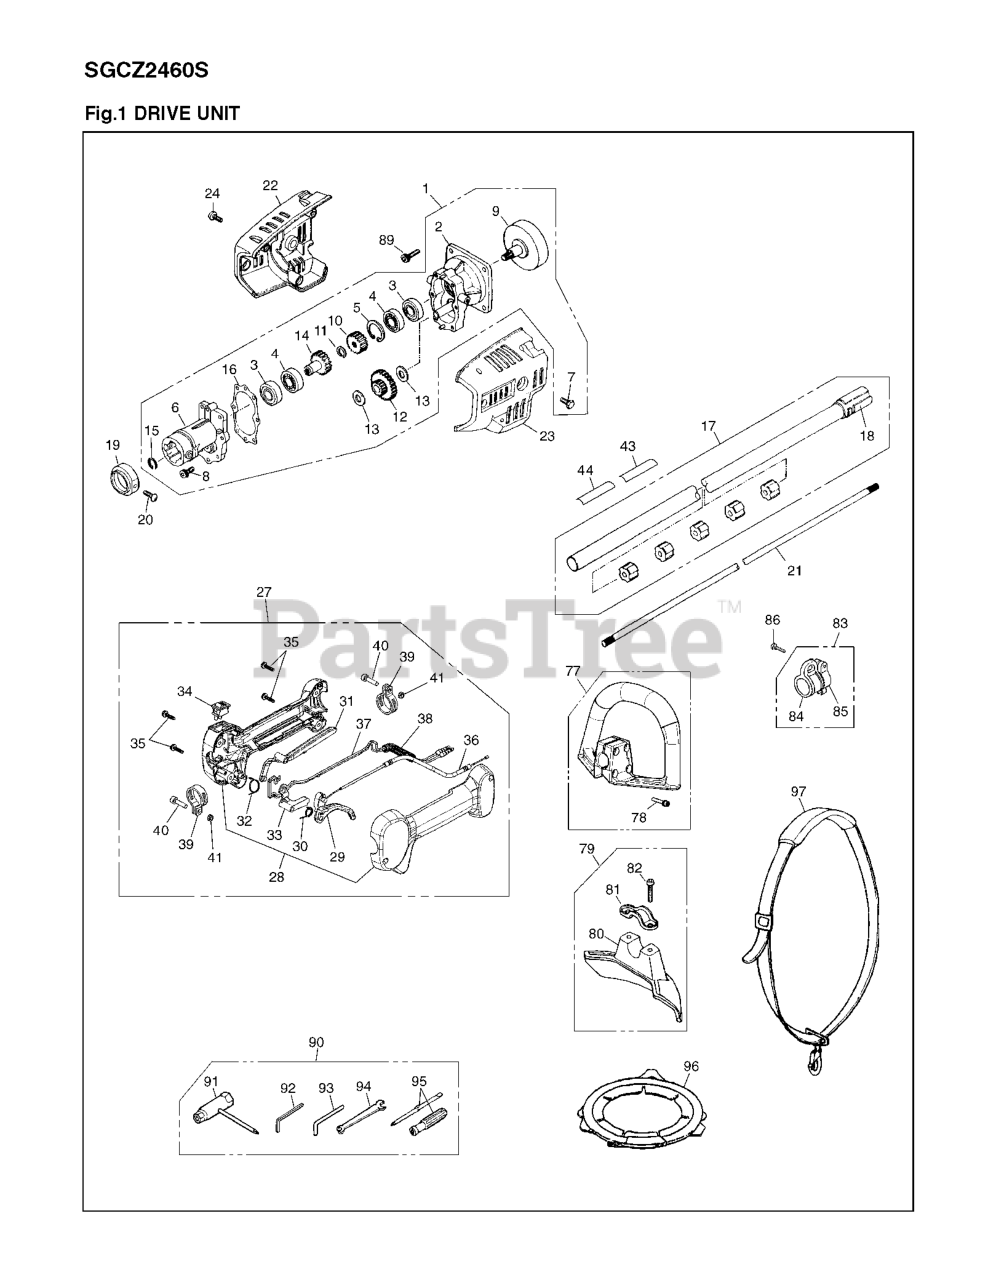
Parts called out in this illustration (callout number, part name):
1	MISSION ASSEMBLY
2	CASE,REAR COMP(RPLS 3805-11101
6	CASE, FRONT
7	BOLT, M6 x 8
8	BOLT
9	DRUM
10	GEAR, PINION
11	RING, SNAP
12	GEAR (RPLS 380511330)
13	WASHER***
14	GEAR, WHEEL
16	GASKET (RPLS 380511411)
17	PIPE COMP (RPLS 380512100)
18	CUSHION (RPLS 380512130)
19	CAP
20	SCREW, M5 x 10
21	SHAFT
22	COVER,RIGHT(RPLS380511510)***
23	COVER, LEFT(RPLS 380511520)***
24	SCREW
27	GRIP ASSY
28	GRIP HALF SET
29	LEVER, THROTTLE
30	SPRING, THROTTLE
31	LEVER FOR GRIP (RPLS -0600)
32	SPRING JOINT
33	LEVER JOINT
36	THROTTLE CABLE
38	TUBE
40	SCREW
41	NUT
43	LABEL
44	LABEL CAUTON FOR BC
77	HANDLE ASSY. (RPLS T319514001)
79	GUARD ASSY (RPLS 3565-24000)
80	GUARD (RPLS 3565-24110)
81	CLAMP (RPLS 580724120)
82	BOLT, M6 x 1.30
83	HANGER COMP.
84	HANGER
86	SCREW
89	%BOLT, M6 x 20
90	TOOL SET
93	Wrench Tool
94	SPANNER,8x10(RPLS 090100810
95	SCREWDRIVER
96	COVER BLADE
97	STRAP ASSY
